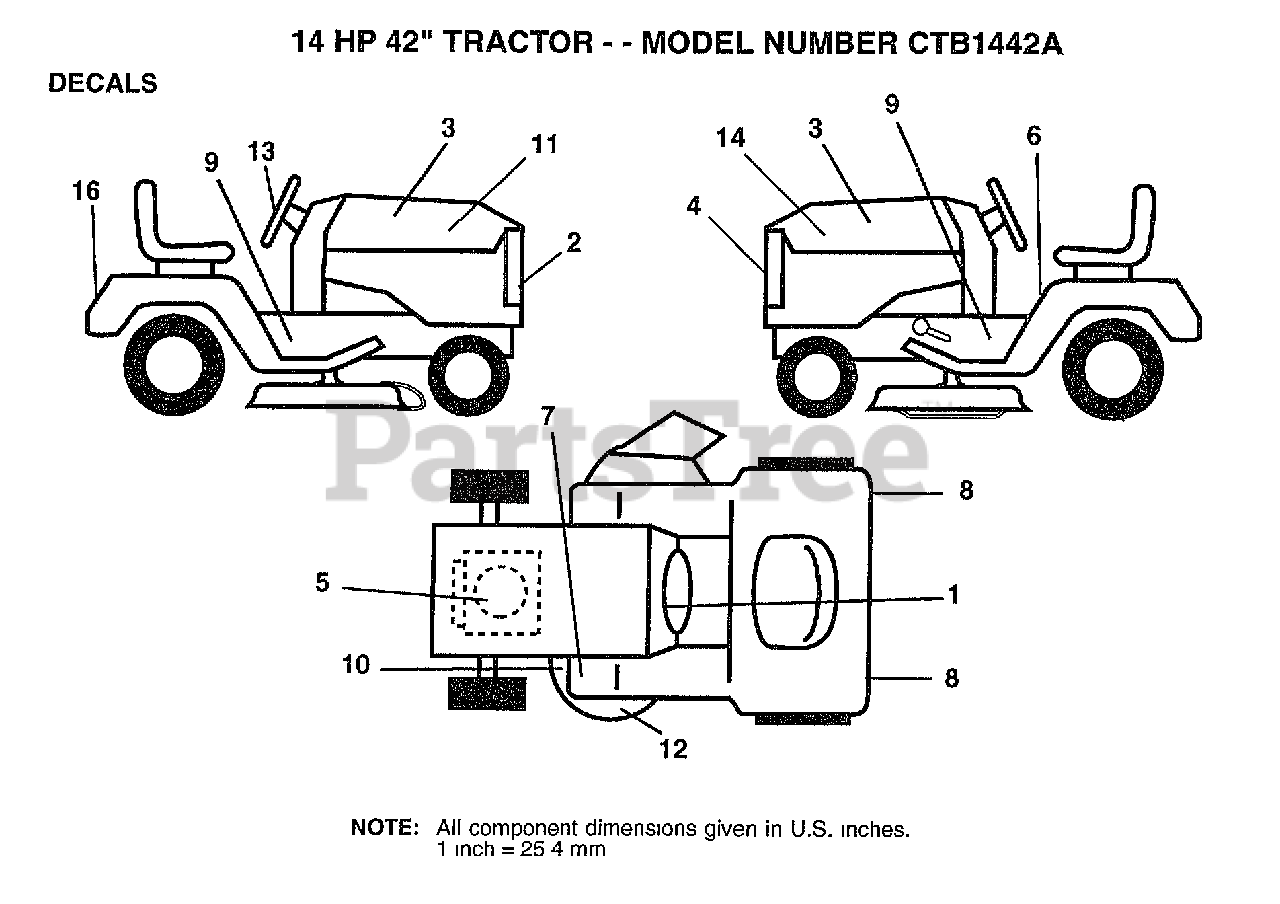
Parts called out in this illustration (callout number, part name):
1	DECAL.DASH.INST.
2	DECAL.GRILLE
3	DECAL.HOOD.14HP
5	DECAL.ENG.272613
6	DECAL
8	REFLECTOR-TAIL YT
9	CHASSIS DECAL
10	DECAL
11	DECAL.HOOD.RH
13	DECAL.STG.WHL.INS
14	DECAL.HOOD.LH
16	DECAL.FENDER
